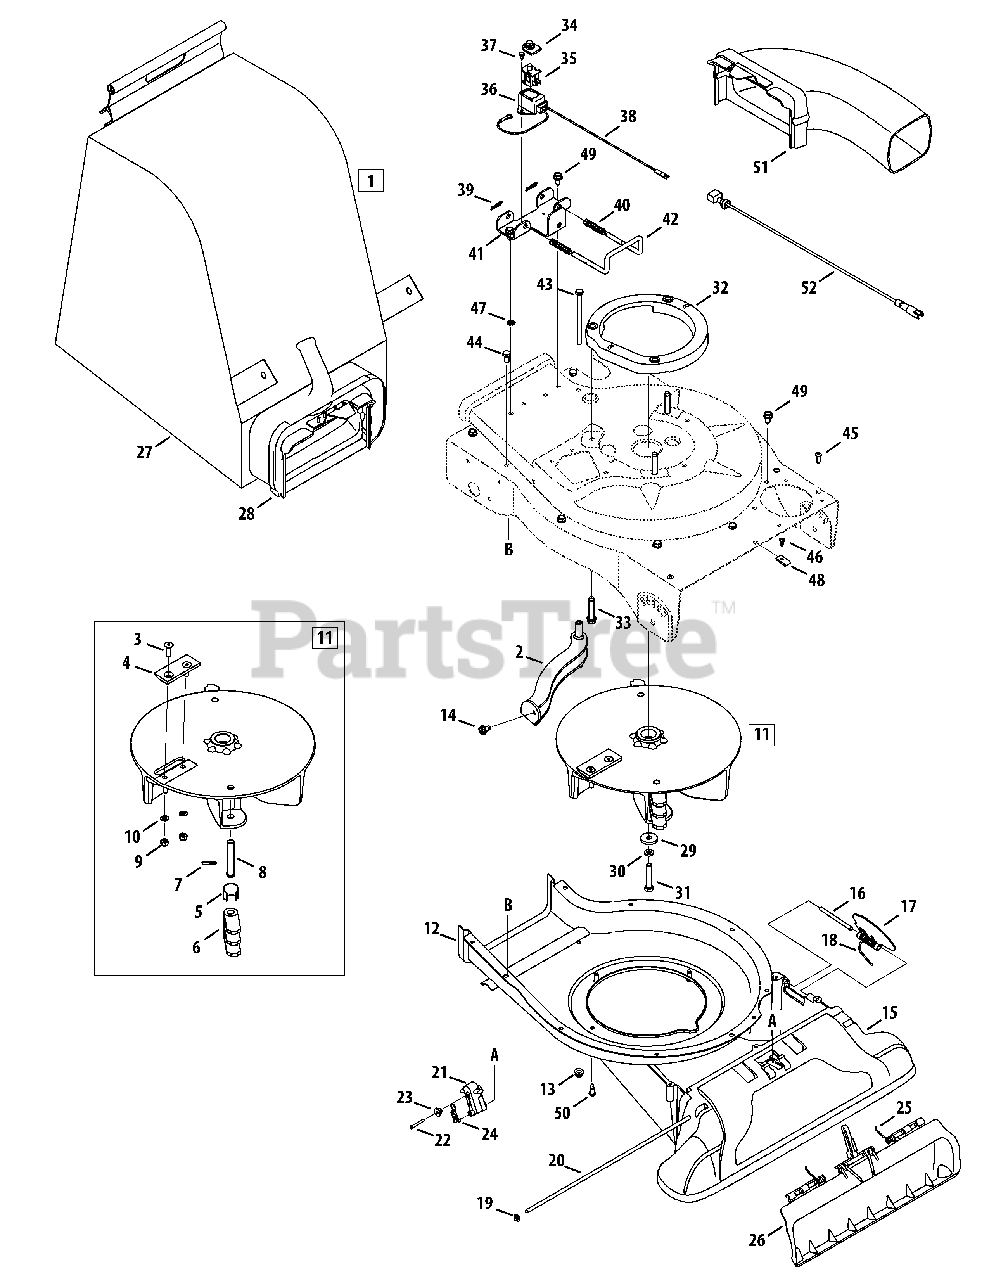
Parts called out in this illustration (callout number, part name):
1	Bag Assembly
2	Screen Assembly
3	Hex Screw 5/16-24 x 1.0
4	Chipper Blade
5	Pin Clip
6	Flail
7	Spiral Pin
8	Clevis Pin
9	Lock Nut, 5/16-24
10	Lock Washer, 5/16
11	Impeller Assembly
12	Lower Flail Housing
13	Flange Lock Nut 5/16-18
14	Screw, 5/16-18 x.500
15	Nozzle (Incl. Ref.# 16-26)
16	Hinge Pin
17	Base Adapter Door
18	Torsion Spring
19	Cap Speed Nut 1/4
20	Pivot Rod
21	Nozzle Door Lever
22	Hex Screw, #8-18 x 1.25
23	Shoulder Spacer
24	Extension Spring
25	Nozzle Door Torsion Spring
26	Nozzle Door
27	Bag
28	Chute Assembly
29	Flat Washer.375 ID x 1.25 OD
30	Lock Washer 3/8
31	Hex Cap Screw, 3/8-24 x 2.75
32	Engine Spacer Assembly
33	Screw, 3/8-16 x 1.875
34	Switch Cover
35	Safety Switch
36	Safety Switch Cover
37	Hex Washer Screw #10-16 x.50
38	Wire Harness
39	Cotter Pin
40	Compression Spring
41	Mounting Bracket
42	Lock Rod
43	Hex Cap Screw 5/16-18 x 4.5
44	Hex Cap Screw 5/16-18 x.625
45	Screw, #12-16 x.750
46	Screw #10 - 16 x.500
47	External L-Washer 5/16
48	Speed Nut
49	Hex Index Screw, 5/16-12 x.750
50	Shoulder Screw, #12-24 x .30 x .46
51	Blower Chute
52	Wire Harness Adapter
